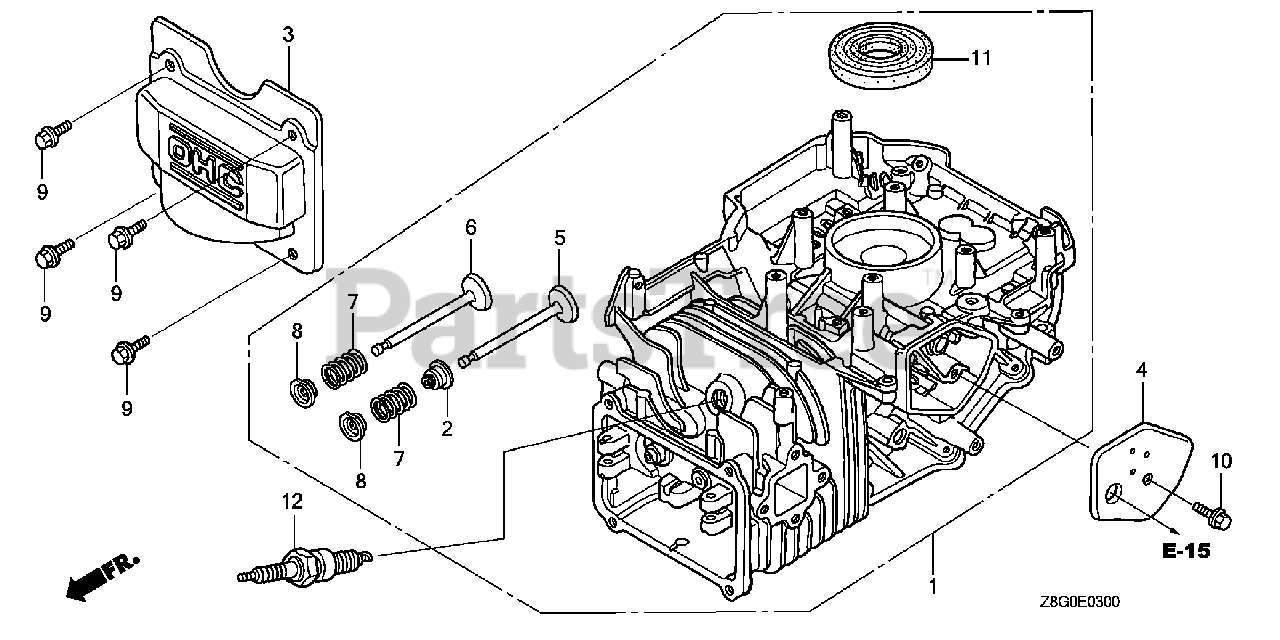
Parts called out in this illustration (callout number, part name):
1	CYLINDER ASSY.
2	SEAL, VALVE STEM
3	COVER, HEAD
4	COVER, BREATHER (BREATHER VALVE ASSY.)
5	VALVE, IN. (ROCKNEL)
6	VALVE, EX.
7	SPRING, VALVE
8	RETAINER, IN. VALVE SPRING
9	BOLT, FLANGE (6X12) (CT200)
10	BOLT, FLANGE (6X14) (CT200)
11	OIL SEAL (25.4X62X6)
12	SPARK PLUG (BPR5ES) (NGK)
12	SPARK PLUG (BPR6ES) (NGK)
